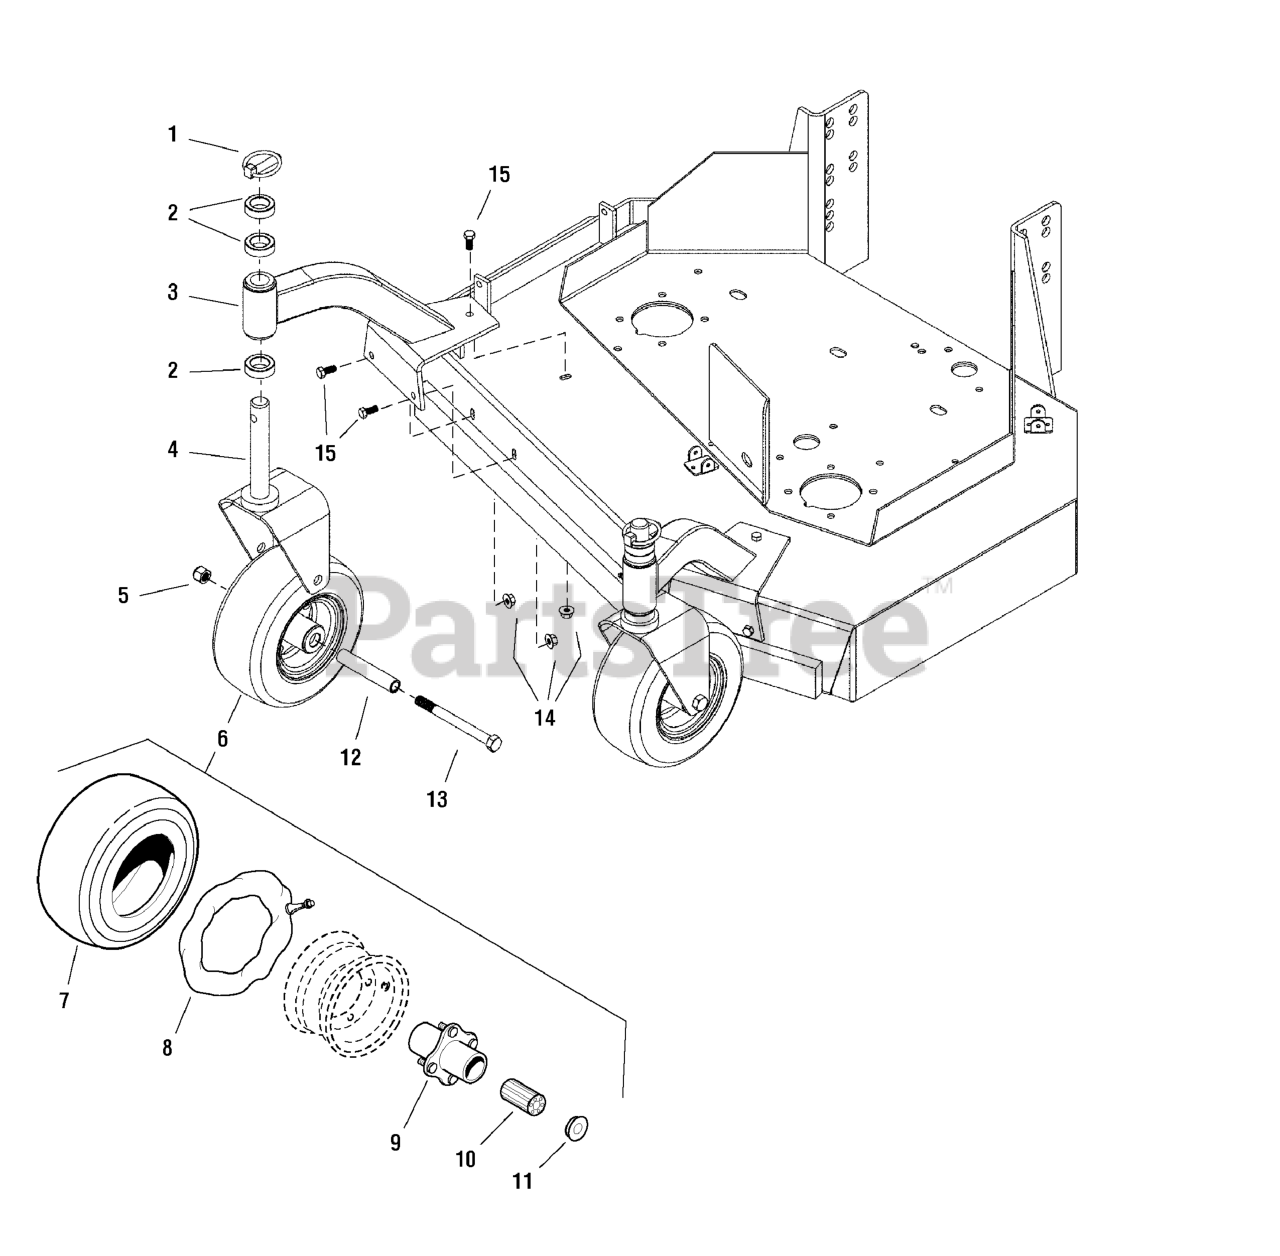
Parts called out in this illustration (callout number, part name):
1	PIN, Lynch
2	SPACER, 1.02 x 1.56 x .50
3	CASTER MOUNT, Complete
3	BUSHING, FLANGE
3	GREASE FITTING
4	YOKE, Caster
5	NUT, 1/2-13 HEX NYLON LOCK
6	TIRE ASSM, 9 X 3.5 X 4, SILVER
7	TIRE, Front, 9 x 3.5 x 4
9	HUB & BEARING ASSEMBLY, Complete, Silver
10	BEARING, ROLLER 3/4" ID X 3.25" (ONE PER TIRE)(SV)
11	RETAINER, Bearing
12	AXLE, Caster Wheel
13	BOLT, 1/2-13 x 5-1/2
14	NUT, 5/16-18 HEX SERRATED FLANGE (LARGE)
15	BOLT, 5/16-18 X 3/4 GD5
